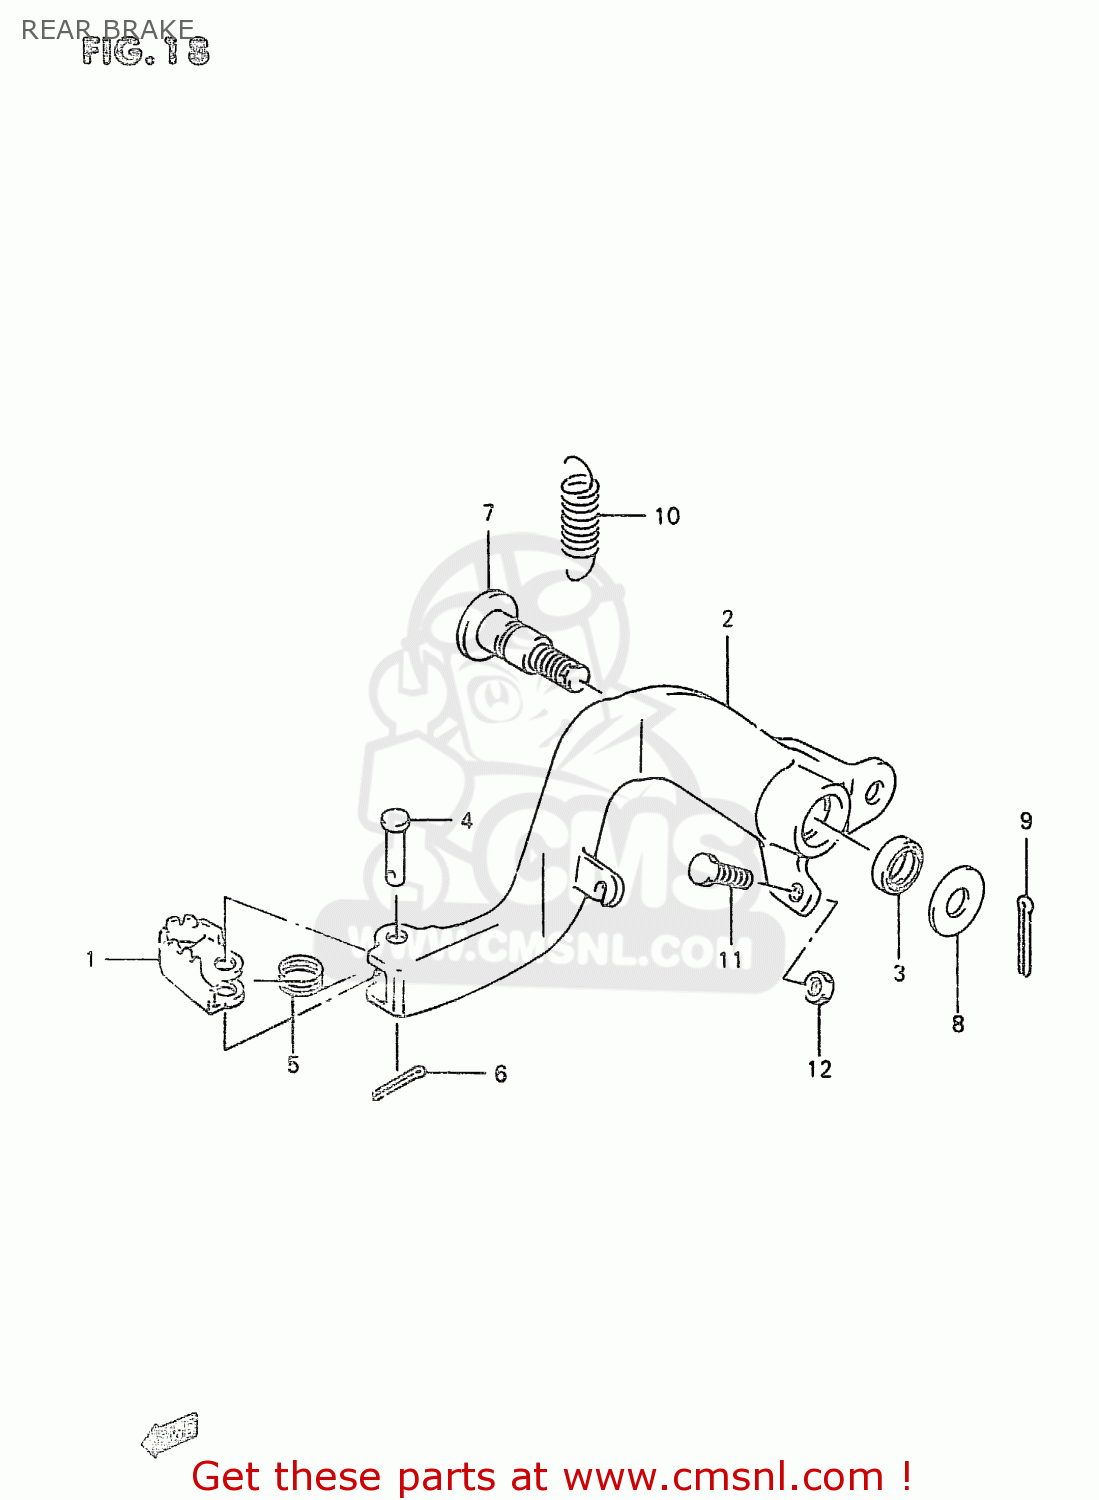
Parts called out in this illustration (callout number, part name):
1	PEDAL,BRAKE
2	ARM,BRAKE PEDAL
3	SEAL,OIL(15X21X3)
4	PIN(6X23.5)
5	SPRING
6	PIN
7	SHAFT,BRAKE PEDAL
8	WASHER
9	PIN 20X20
10	SPRING,BRAKE PEDAL RETURN
11	BOLT(6X23)
12	NUT 6MM
